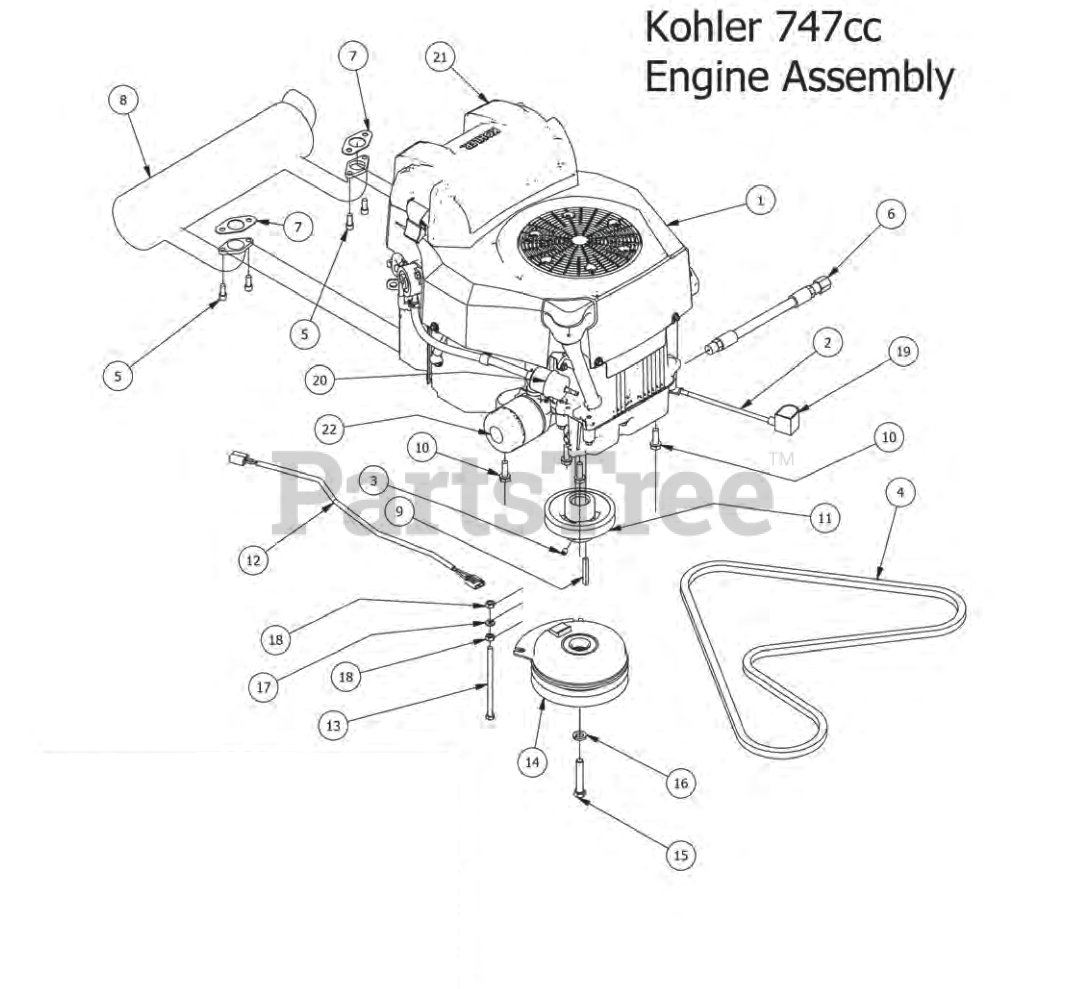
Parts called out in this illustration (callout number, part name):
1	Kohler-2014 CZT/Outlaw 747cc
2	Starter to chassis cable
3	5/16 Set Screw
5	5/16-18 x 3/4 Socket C/S
6	Oil drain Valve
7	Exhaust Gasket
8	Kohler Exhaust
9	1/4 x 2 Square key Stock
10	3/8 x 1 1/8 bolt
11	4 3/4 Motor Pulley
12	Clutch Pigtail
13	5/16-18 x 5-1/2 GR 5 Hex Bolt
14	Clutch Assembly
15	7/16" x 2 1/2" Hex Bolt
16	7/16" Lock Washer
17	5/16" Lock Washer
19	Black Boot For ground cable
20	725 & 747 Kohler Fuel Filter ZT/MZ
21	725 Kohler air filter CZT/Outlaw
22	725 & 747 Kohler Oil Filter
